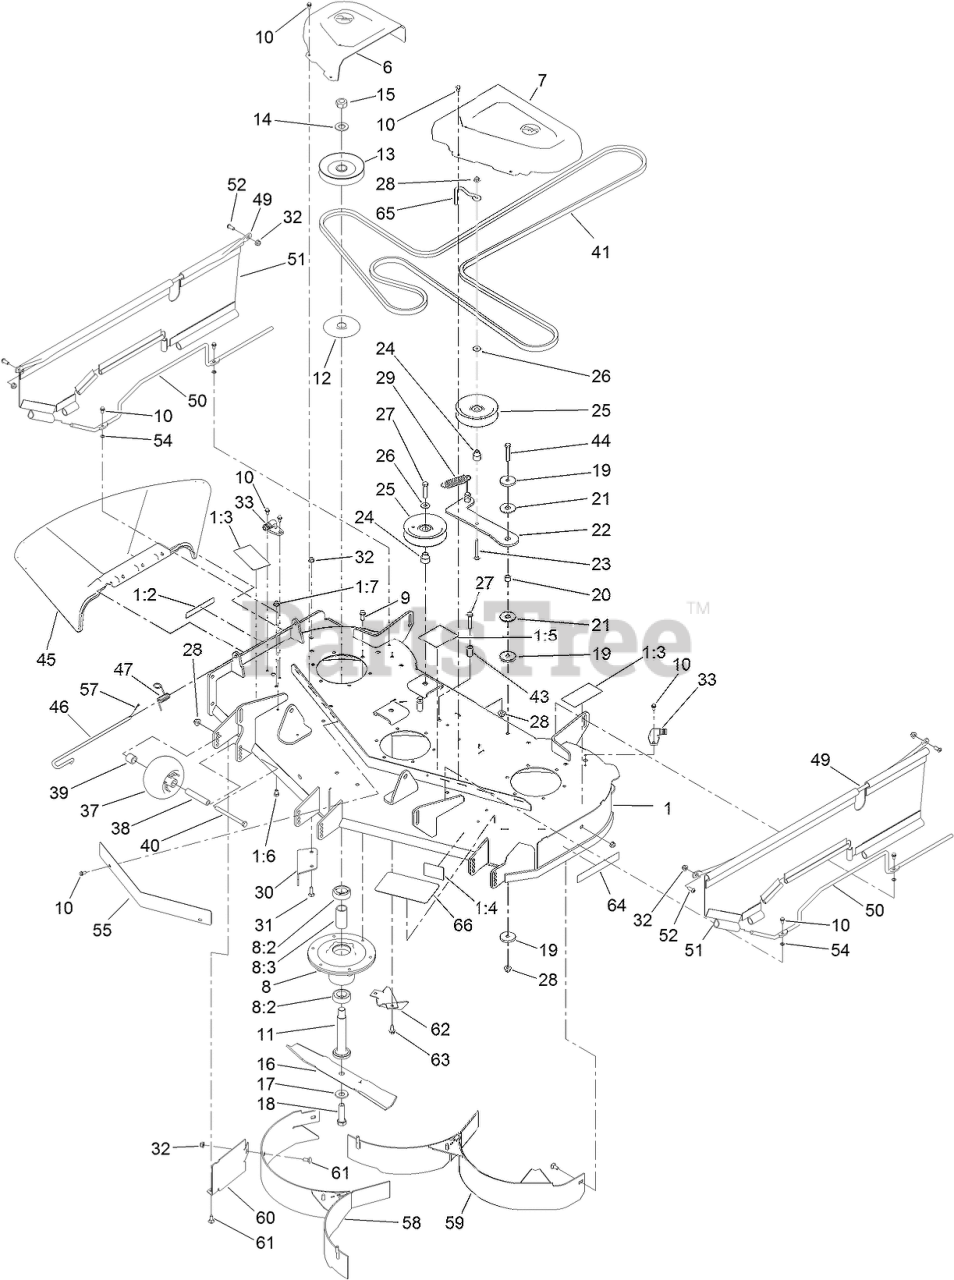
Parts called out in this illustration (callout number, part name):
1	DECK ASM
1:2	DECAL-DANGER
1:3	DECAL-DANGER, DECK
1:4	DECAL-SCALP, ANTI
1:5	DECAL-ROUTING, BELT
1:6	SCREW-HH
1:7	NUT-HF, NI
6	COVER-BELT, RH
7	COVER-BELT, LH
8	SPINDLE ASM
8:2	BEARING-BALL
8:3	SPACER-BEARING
9	SCREW-TAPTITE
10	SCREW-HWH
11	SHAFT-SPINDLE
12	SHIELD-BEARING
13	PULLEY
14	WASHER
15	NUT-HEX
16	BLADE-MULCH, 16.50 INCH
17	WASHER-BELLEVILLE
18	SCREW-BLADE
19	WASHER-PLAIN
20	BUSHING-LEVER, LIFT
21	WASHER-FRICTION, COMPOSITE
22	ARM-IDLER
23	SCREW-CARR
24	BUSHING-IDLER
25	PULLEY-IDLER, FLAT
26	WASHER-HARDENED
27	SCREW-HH
28	NUT-HF, NI
29	SPRING-EXTENSION
30	BAFFLE-CUTOFF
31	SCREW-CARR
32	NUT-HF, NI
33	FITTING-WASHOUT
37	ROLLER-SCALP, ANTI
38	TUBE-SPANNER
39	SPACER-AXLE, REAR
40	SCREW-HH
41	V-BELT
43	SPACER
44	SCREW-HH
45	DEFLECTOR-DISCHARGE
46	PIN-CHUTE
47	SPRING-TORSION
49	ROD SUPPORT, UPPER
50	ROD SUPPORT, LOWER
51	SIDE GUARD ASM
52	SCREW-HSBH
54	NUT-RETAINING
55	SHIELD-FRONT
57	PIN-COTTER
58	BAFFLE-RECYCLER
59	BAFFLE-RECYCLER
60	GUARD-BAFFLE
61	BOLT-CARR
62	KICKER-FLANGED
63	SCREW-HWHTF
64	DECAL-RECYCLER
65	BELT GUIDE - IDLER
66	TREAD-STEP
